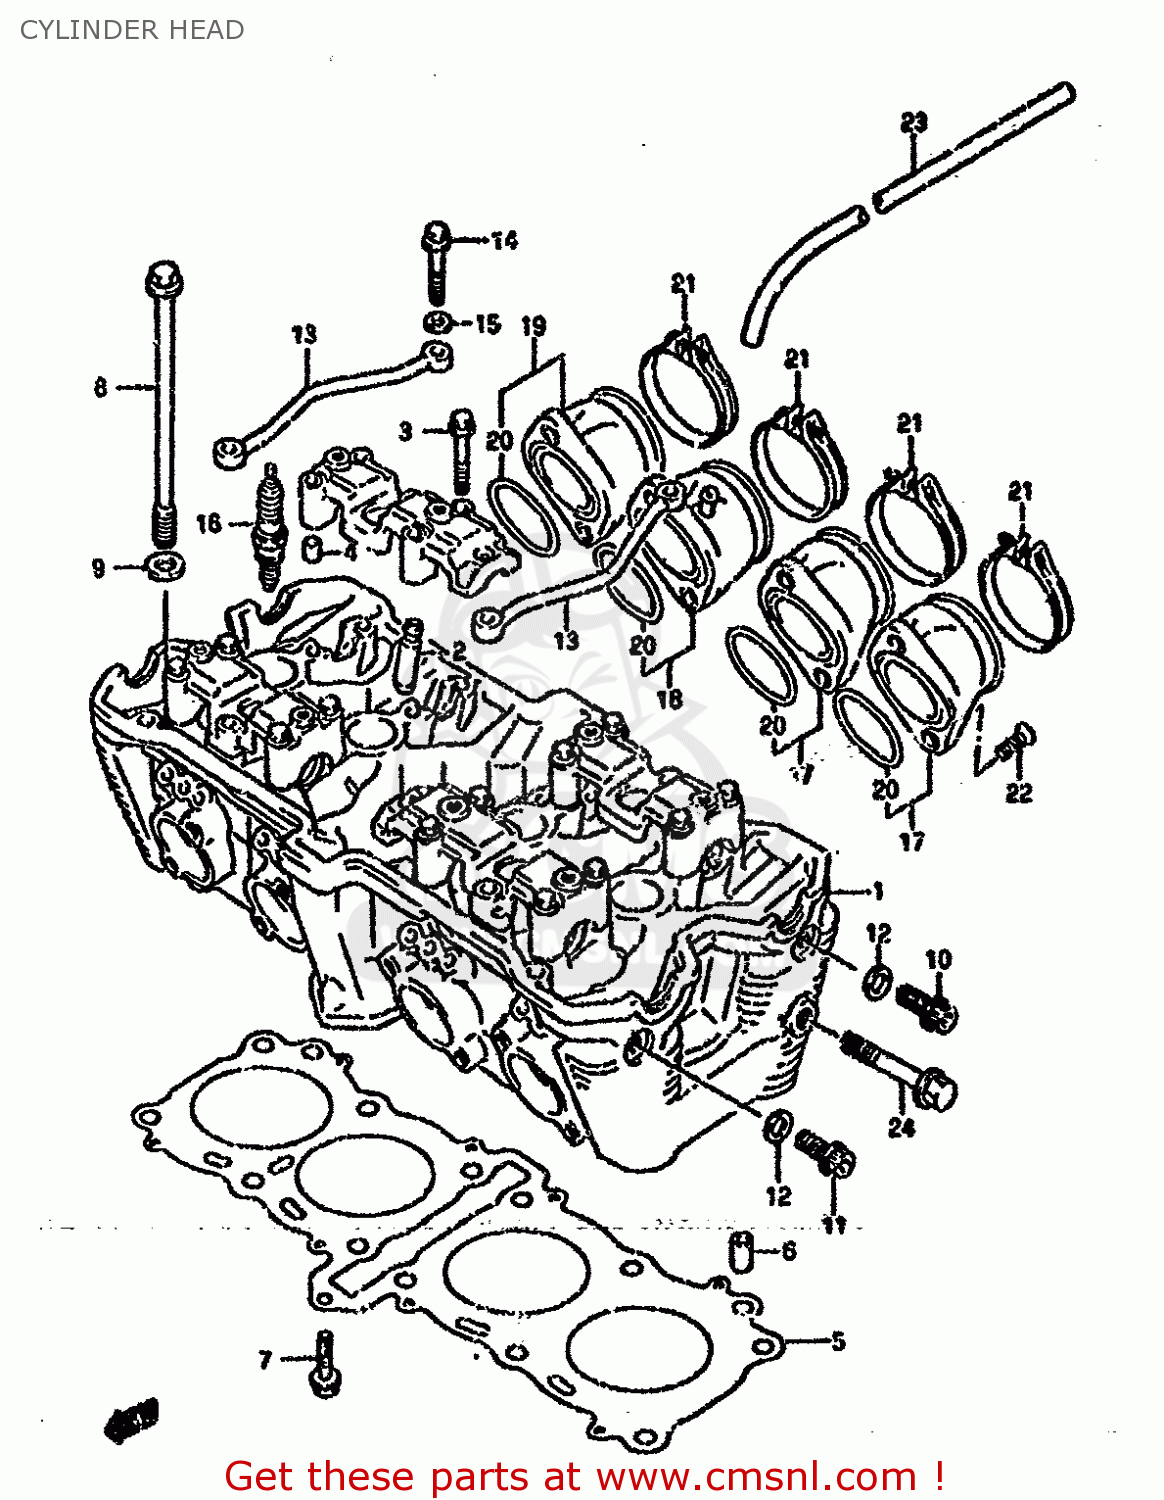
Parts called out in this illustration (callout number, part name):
1	HEAD ASSEMBLY,CYLINDER
2	GUIDE,VALVE
3	BOLT(6X45)
4	PIN(6.2X8X11)
5	GASKET,CYLINDER HEAD
6	PIN
7	BOLT
8	BOLT(10X160)
9	WASHER(10.5X19X2)
10	BOLT
11	BOLT
12	GASKET(8.2X14X1).6 (NAS)
13	PIPE,CYLINDER HEAD OIL
14	BOLT(6X39)
15	WASHER
16	PLUG,SPARK(CR8E)
17	PIPE,INTAKE NO.1
18	PIPE,INTAKE NO.3
19	PIPE,INTAKE NO.4
20	O RING(D:2.4,ID:44)
21	CLAMP
22	SCREW(6X16)
23	HOSE,VACUUM
24	BOLT
